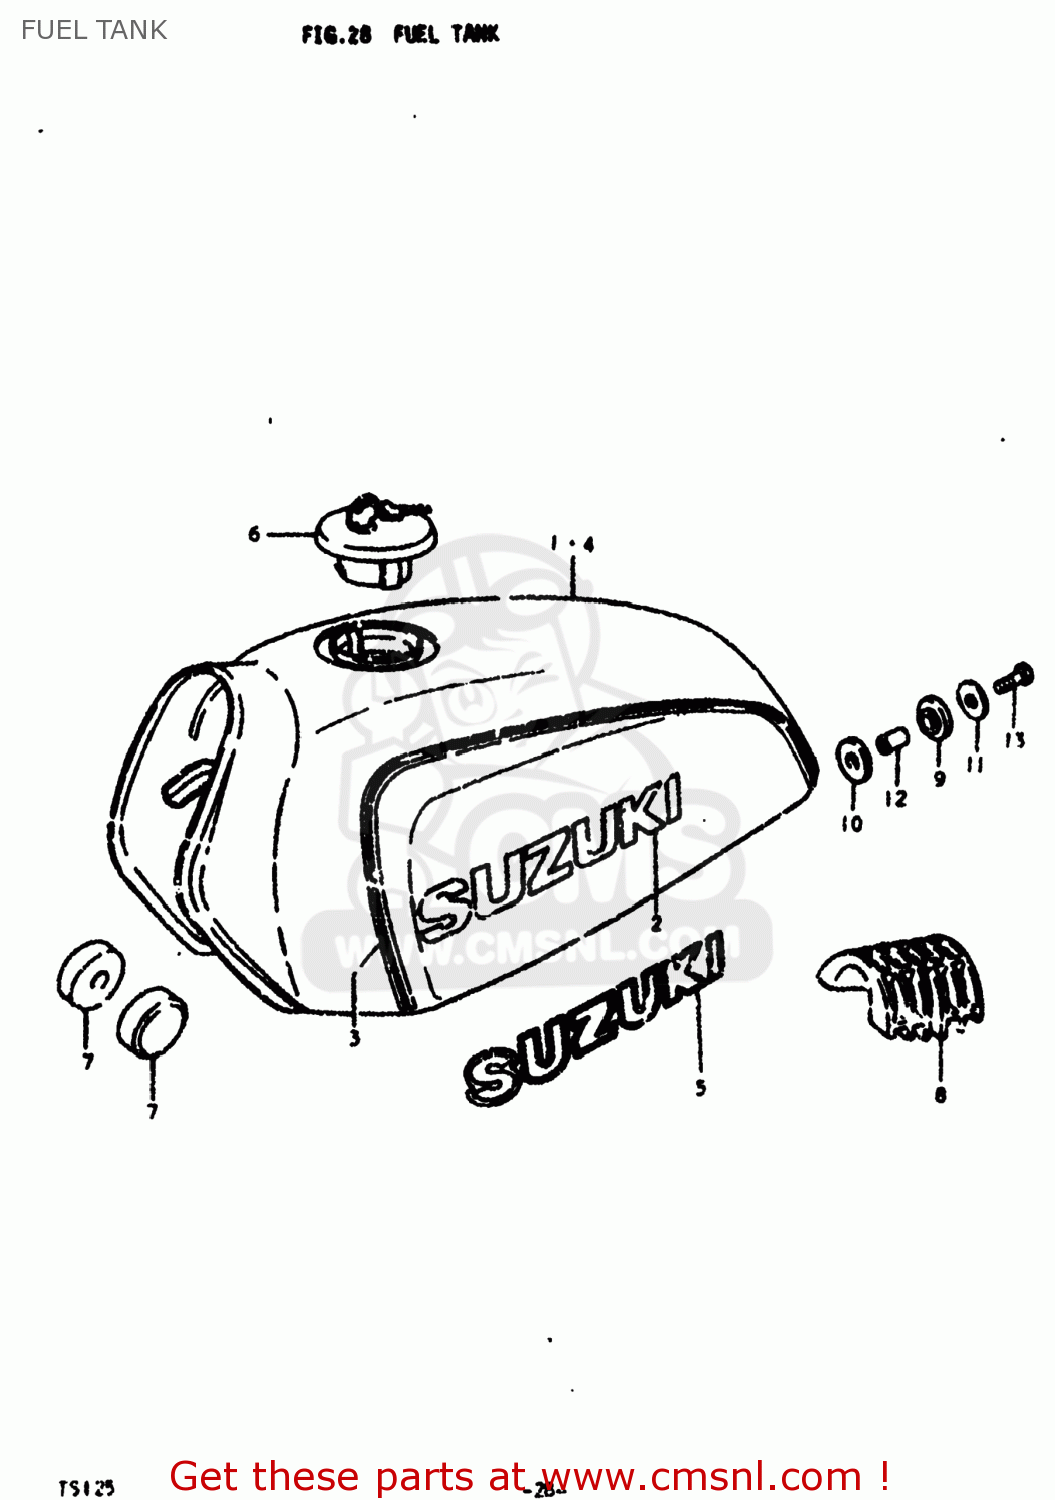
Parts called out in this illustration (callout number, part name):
1	TANK ASSEMBLY,FUEL
2	EMBLEM
4	TANK ASSEMBLY,FUEL
5	EMBLEM
6	CAP SET,FUEL TANK
7	CUSHION
8	CUSHION
9	CUSHION
10	CUSHION
11	WASHER (8.5X29X1.6)
12	SPACER (8.2X12X17)
13	BOLT
